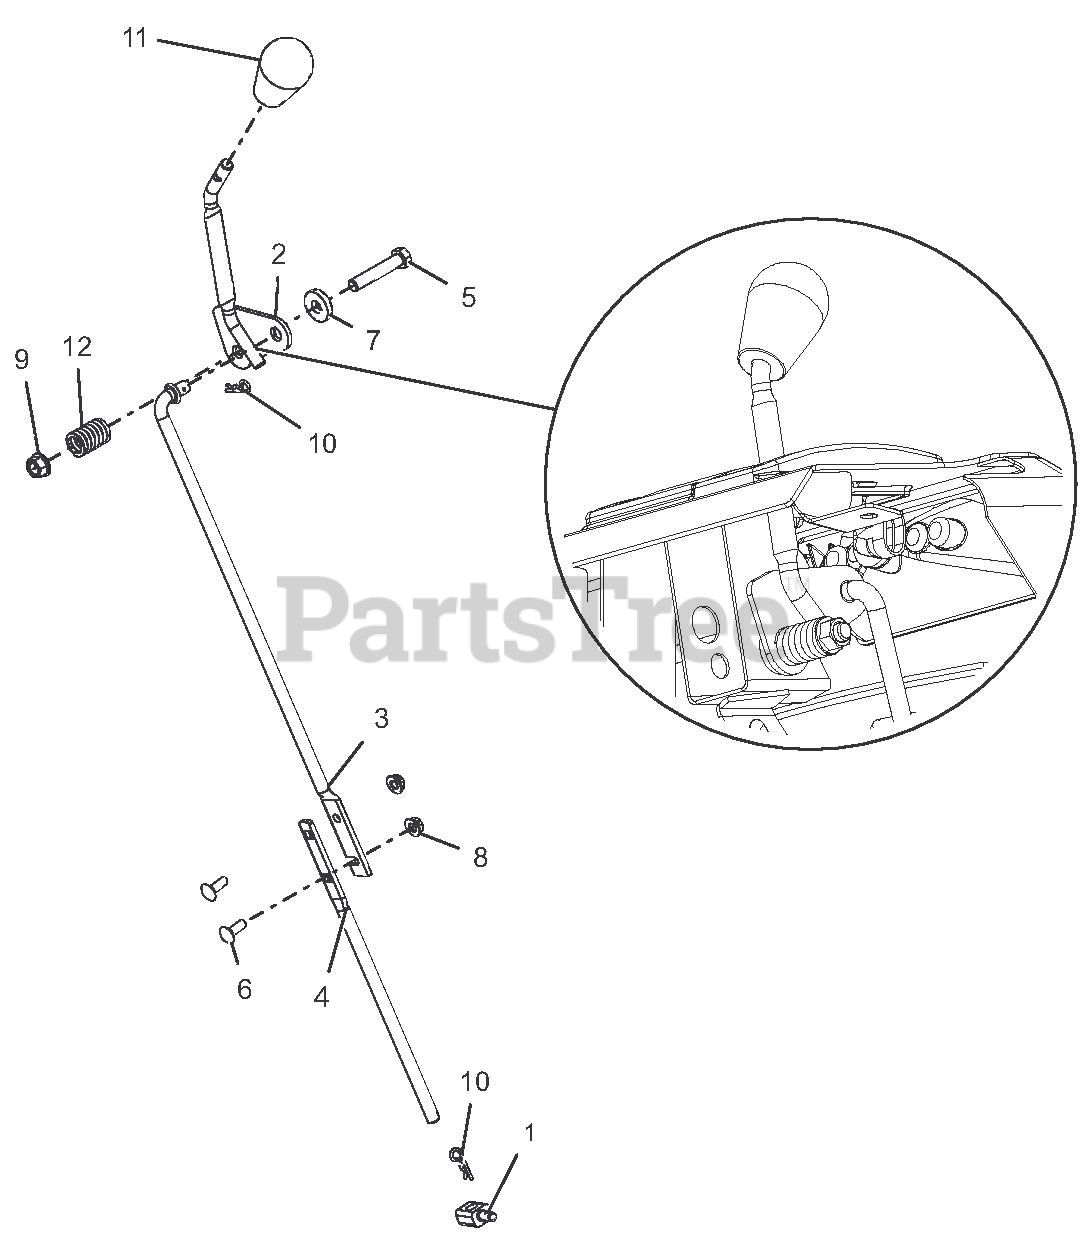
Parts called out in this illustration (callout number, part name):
1	PIVOT, SHIFT ROD .375-16 (TRUNN)
2	WLDMT, CONTROL LEVER (SHIFT)
3	ROD, SHIFT - UPPER
4	ROD, SHIFT - LOWER
5	BLT-HEX .38-16X2.00 GR5 YWZC
6	BLT-RDHDSQNK .25-20X.75 G5 YWZC
7	WSHR-FL-STL .406X1.00X.188 YWZC
8	NUT, LK-CTR-FLG .25-20 YWZC
9	NUT, LK-TOP-FLG .38-16 YWZC
10	PIN, HAIR INT .08X.18X1.18 YWZC
11	KNOB, SOFT TEARDROP, PUSH-ON GRY
12	SPRG, COMPRESSION
